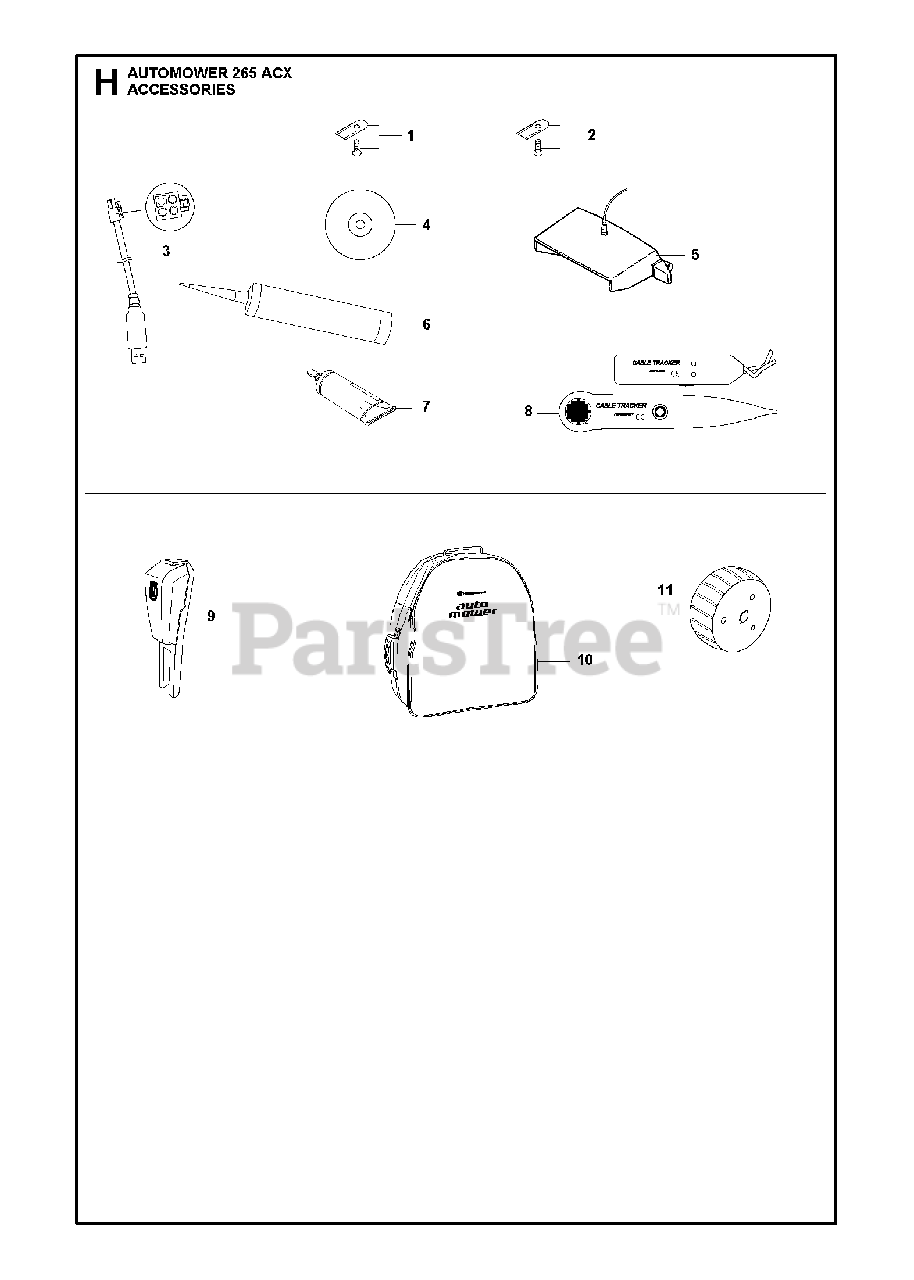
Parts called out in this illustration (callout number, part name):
1	BLADE
1	BLADE KIT
1	BLADE - 30 PCS
1	BLADE - BULK PACK 500 PCS
2	BLADE 9PCS EXTRA THICK
2	Blade Set, 9 Piece Extra Thick
2	BLADE CARBON STEEL, THICK BLAD
2	BLADE 300PCS -SINGLE HOLE THIC
3	USB SERVICE CABLE
5	N/A PIN CODE TRANSFER UNIT ADA
7	SEALANT
8	TEST EQUIPMENT
9	SIGNAL BOOSTER
11	WHEEL ASSY
11	HEAVY FRONT WHEEL KIT
